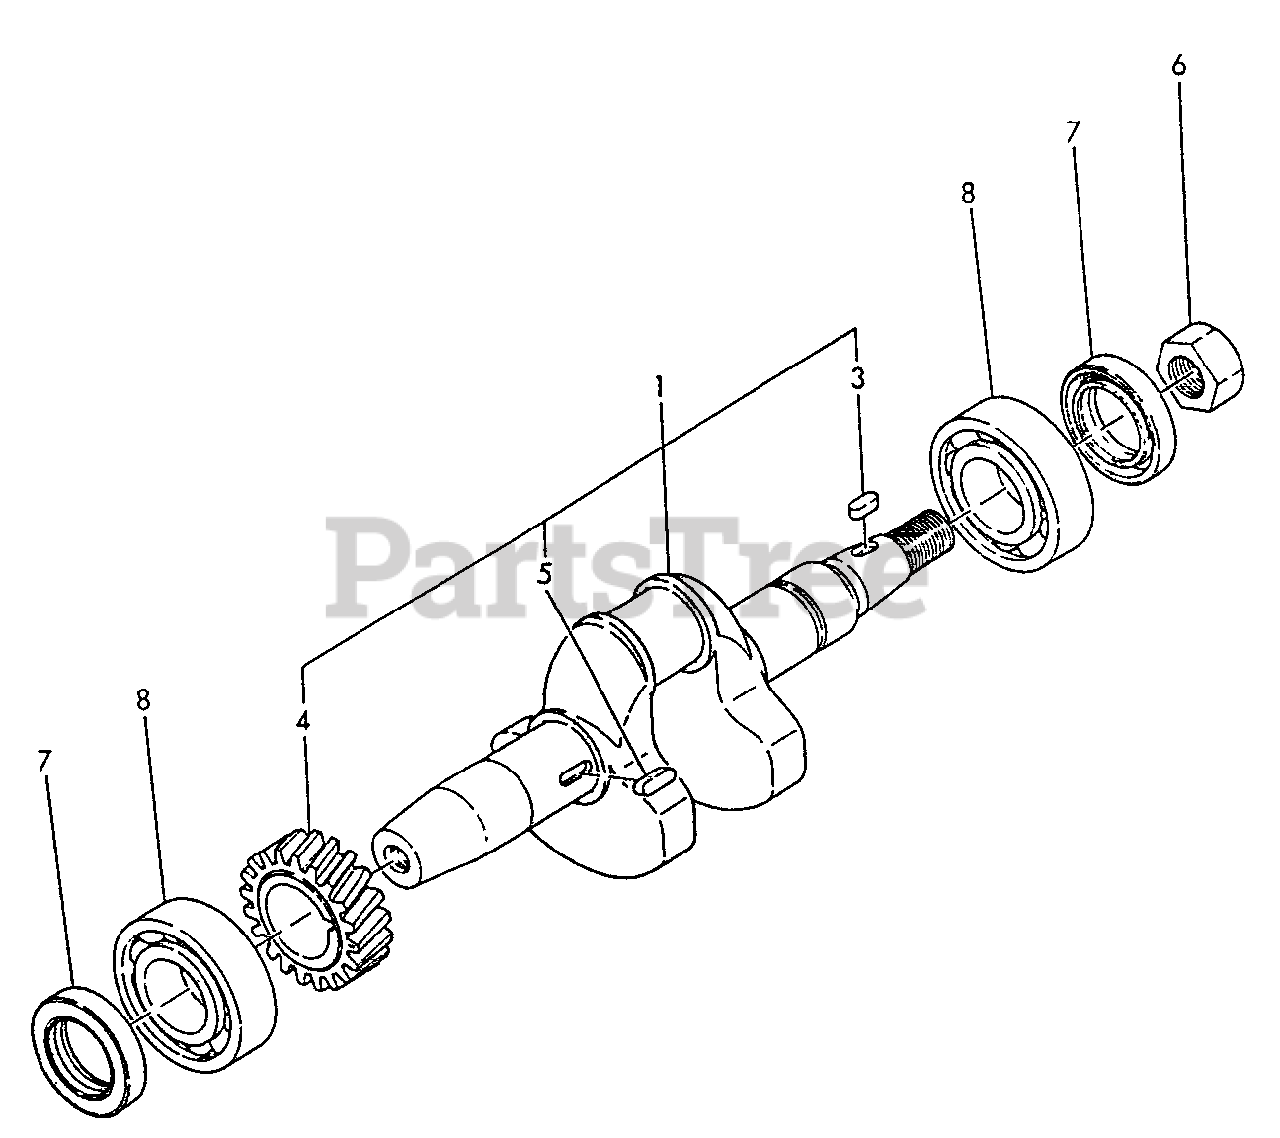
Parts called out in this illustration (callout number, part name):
1	CRANKSHAFT ASSY
3	KEY - 4×10
4	GEAR, CRANKSHAFT
5	KEY 4×12
6	NUT - 14
7	SEAL, OIL
8	BEARING, BALL
